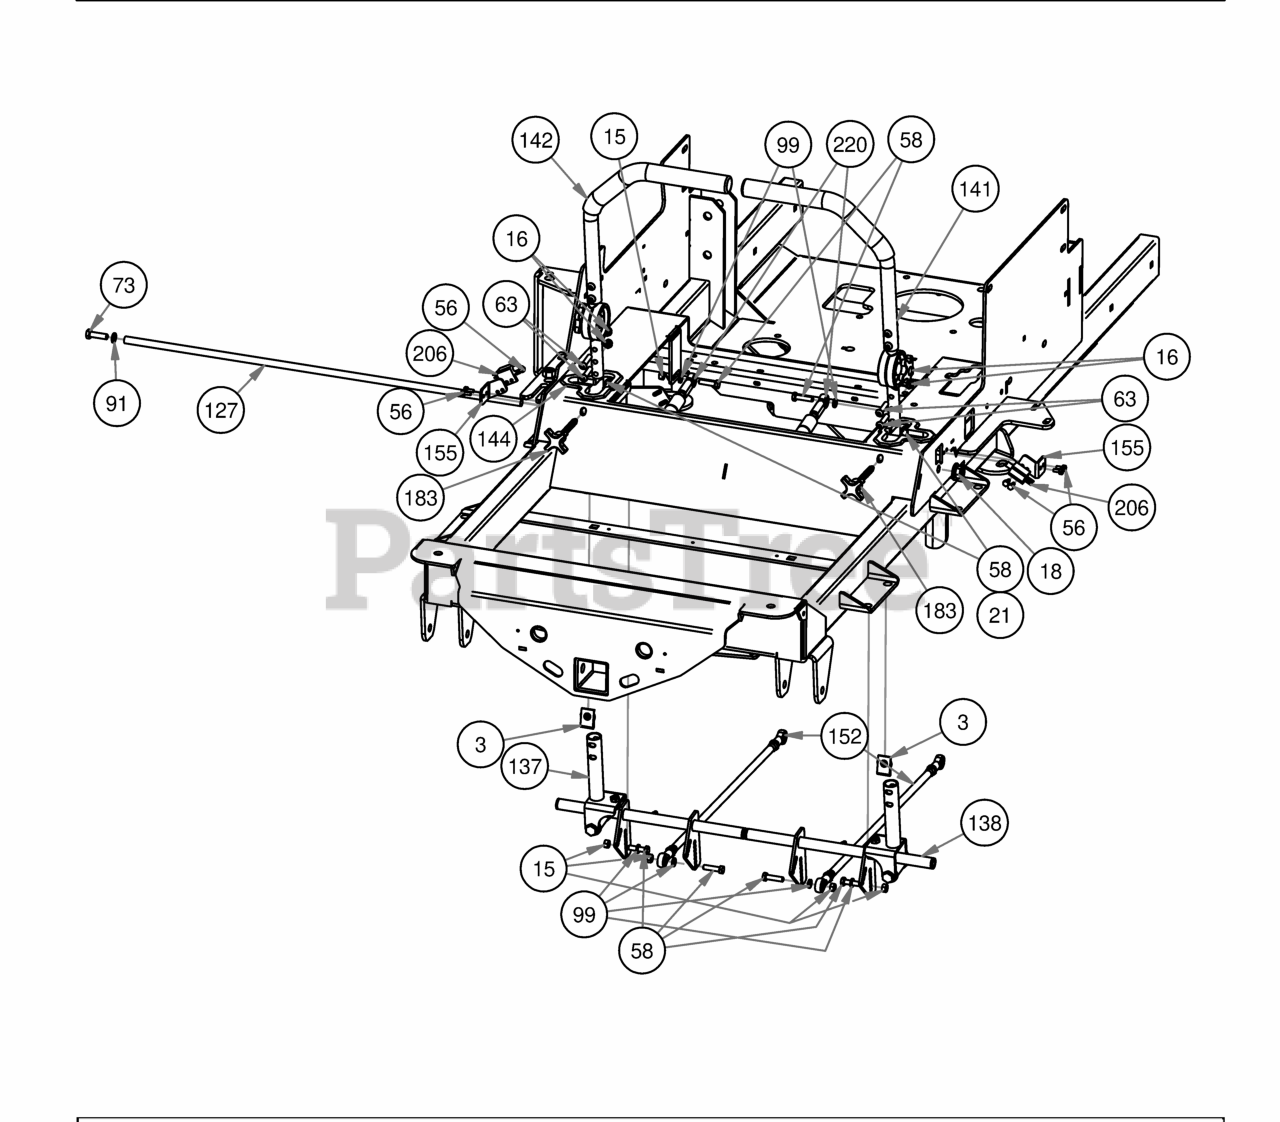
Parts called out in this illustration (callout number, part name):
3	Extruded Nut 3/8"-16 3/4" Hole Center With Patch
16	5/16-18 Nylock Insert Locknut
18	1/2-13 Nylon Flange Nut
21	5/16" Flange Nut
56	12-24x 1/2 HWH Bolt
58	5/16 x 1 1/4 Hex Bolt
63	5/16-18 UNC X 1-3/8" BHCS, TORX DRIVE, GR 5
73	3/8" x 1 1/4" Hex Bolt
91	3/8" Lock Washer
99	5/16" Lock Washer
127	2019 Steering Actuator Rod
137	2019 R Series RH Arm Rod Assembly
138	2019 R Series LH Arm Rod Assembly
141	2019 Left Hand ADJ. Steering Arm Kit
142	2019 Right Hand ADJ. Steering Arm Kit
144	Snap-In Bushing-2019
152	2019 Outlaw Gen2 XP Push Rod Assembly
155	2019 Arm Switch Bracket
183	Speed Limiting Knob 3/8-16X 3"
203	2019 Veritical Suspension Frame
206	Safety Switch
220	2019 SROID Damper With Spherical Rod Ends
